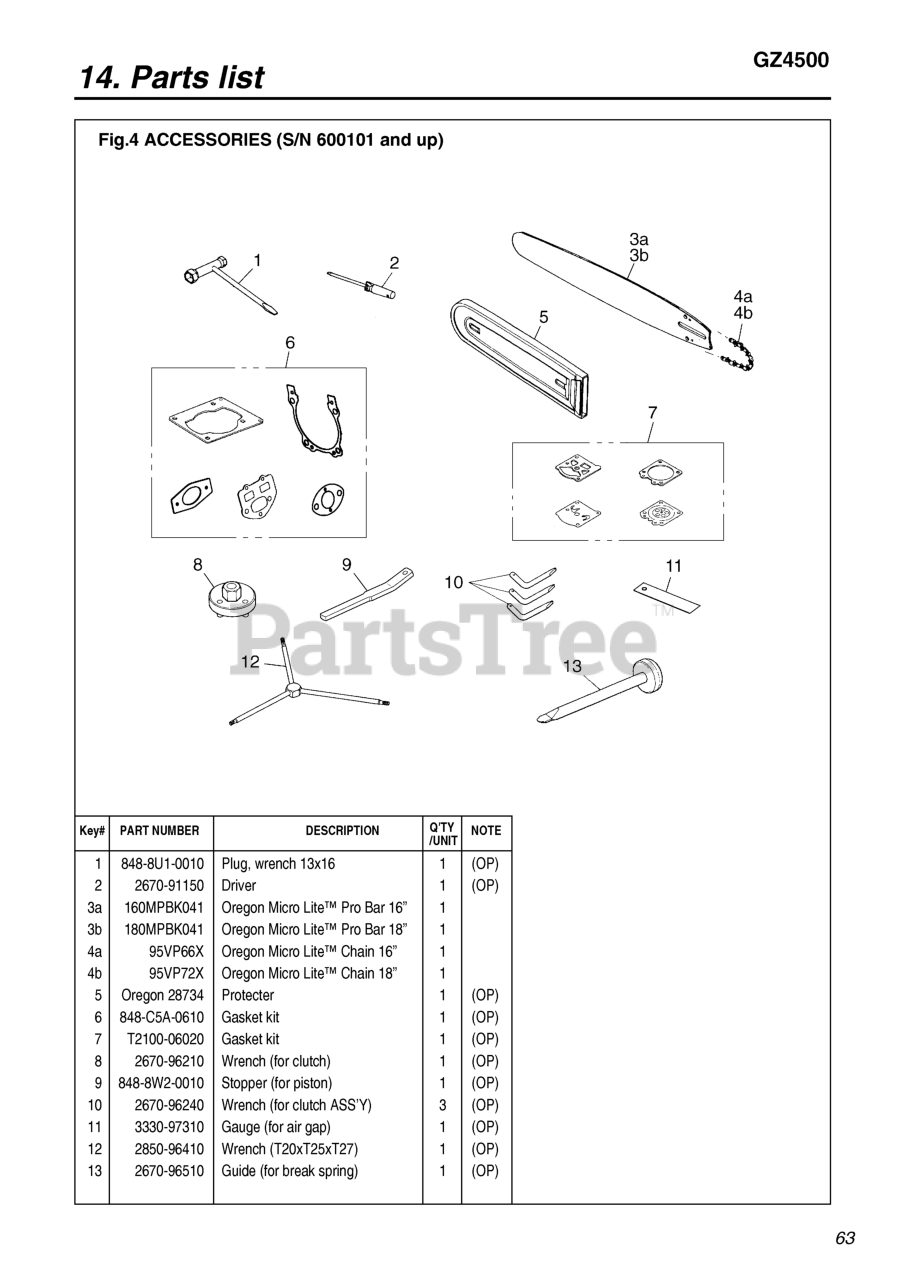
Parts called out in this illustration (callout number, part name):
1	WRENCH
2	SCREWDRIVER
3A	OREGON MICRO LITE PRO BAR 16
3B	OREGON MICRO LITE PRO BAR 18
4A	CHAIN 16
4B	OREGON MICRO LITE CHAIN 18
6	GASKET KIT
7	KIT, GASKET (G3800AVS)
8	WRENCH (TOOL)
9	STOPPER
10	WRENCH (TOOL)
11	GAUGE (TOOL)
12	WRENCH (RPLS. 2670-96410)
13	GUIDE (TOOL)
